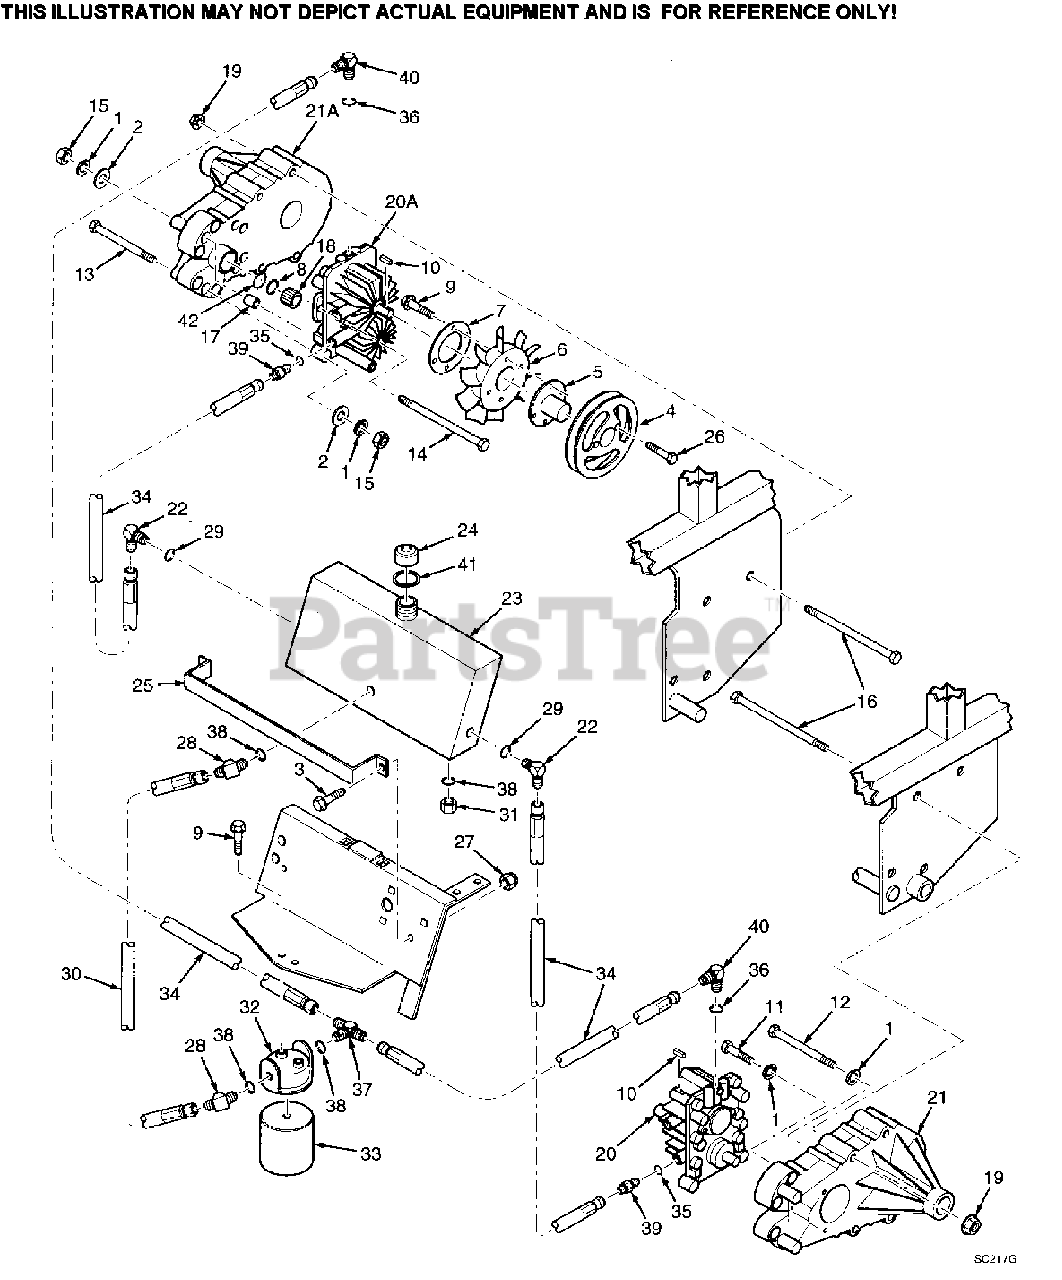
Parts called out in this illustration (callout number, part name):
1	LOCKWASHER, 5/16"
2	FLATWASHER, 5/16"(.344 X .688 X .065)
3	BOLT, SERRATED FLANGE HEX HEAD 1/4-20 X 3/4"
4	PUMP, PULLEY
5	TAPERED HUB, 15 MM BORE
6	FAN
7	WASHER, BACK-UP
8	SNAP RING
9	BOLT, SERRATED FLANGE HEX HEAD 1/4-20 X 1/2"
10	KEY, 5 MM X 5 MM X 25 MM
11	BOLT, HEX HEAD 5/16-18 X 1-3/4"
12	BOLT, HEX HEAD 5/16-18 X 4-1/2"
13	BOLT, HEX HEAD 5/16-18 X 5"
14	BOLT, HEX HEAD 5/16-18 X 7-1/2"
15	NUT, HEX 5/16-18
16	BOLT, HEX HEAD 3/8-16 X 4"
17	SPACER
18	GEAR
19	NUT, SERRATED FLANGE HEX HEAD 3/8-16
20	PUMP, LH(INCLUDES SPACERS)
20A	PUMP, RH(INCLUDES SPACERS)
21	AXLE, LH(INCLUDES BRAKE LEVER)
21A	AXLE, RH(INCLUDES BRAKE LEVER)
22	ELBOW, 90 DEGREE 9/16-18 JIC TO 9/16-18
23	OIL TANK RESERVOIR
24	CAP, OIL RESERVOIR
25	STRAP, OIL RESERVOIR
26	BOLT, HEX HEAD 1/4-20 X 1-1/4"
27	NUT, ELASTIC STOP 1/4-20
28	ELBOW, 45 DEGREE 3/4-16 JIC TO 3/4-16
29	"O" RING, 5/64 X 15/32 ID
30	HOSE ASSEMBLY, FILTER INLET
31	PLUG, 3/4-16 "O" RING
32	HEAD, OIL FILTER
33	OIL FILTER, SPECIAL
34	HOSE ASSEMBLY
35	"O" RING, 3/32 X 3/4 ID
36	"O" RING, 1/16 X 3/8 ID
37	1/2" T-FITTING, 3/4-16 JIC TO 3/4-16
38	"O" RING, 3/32 X 5/8 ID
39	TUBE UNION 3/4-16 JIC TO 7/8-14 "O" RING
40	ELBOW, 90 DEGREE 9/16-18 JIC TO 7/16-20
41	GASKET, HYDRAULIC TANK CAP
42	"O" RING
